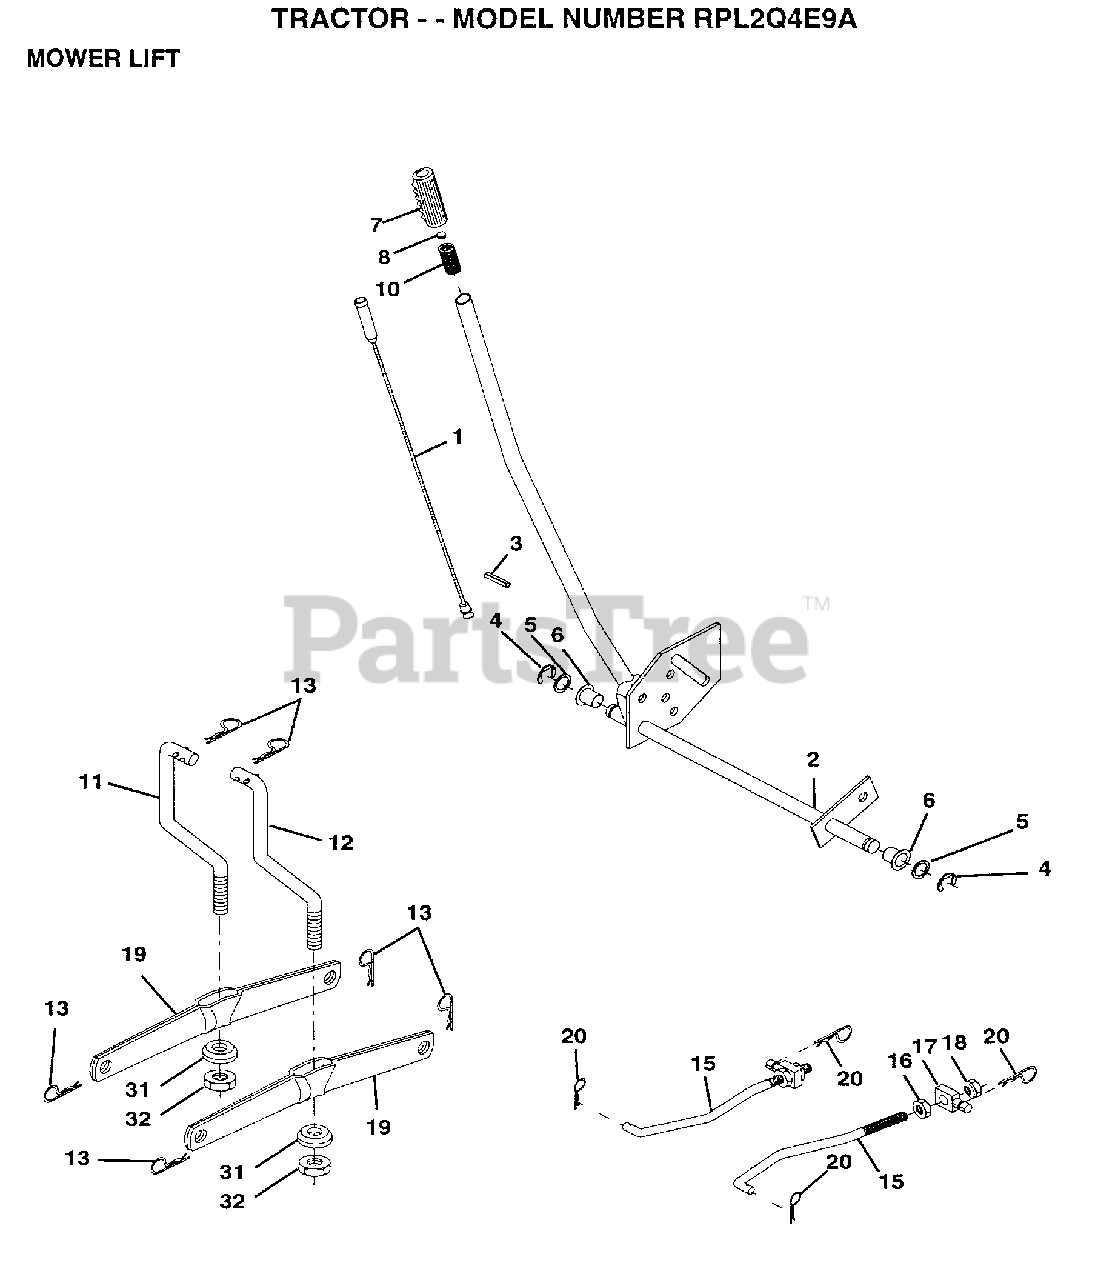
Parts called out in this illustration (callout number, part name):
1	WIRE ASM
2	HANDLE.LIFT.LH.
3	PIN GROOVE
5	WASHER
6	NYLON BEARING
7	GRIP
15	LINK.FRONT
16	NUT
17	TRUNION
18	NUT.LK.W/WSH.1/2.
19	ARM SUSP REAR
20	RETAINER.SPRING
31	BEARING PVT LH
32	NUT.CROWNLOCK.3/8
